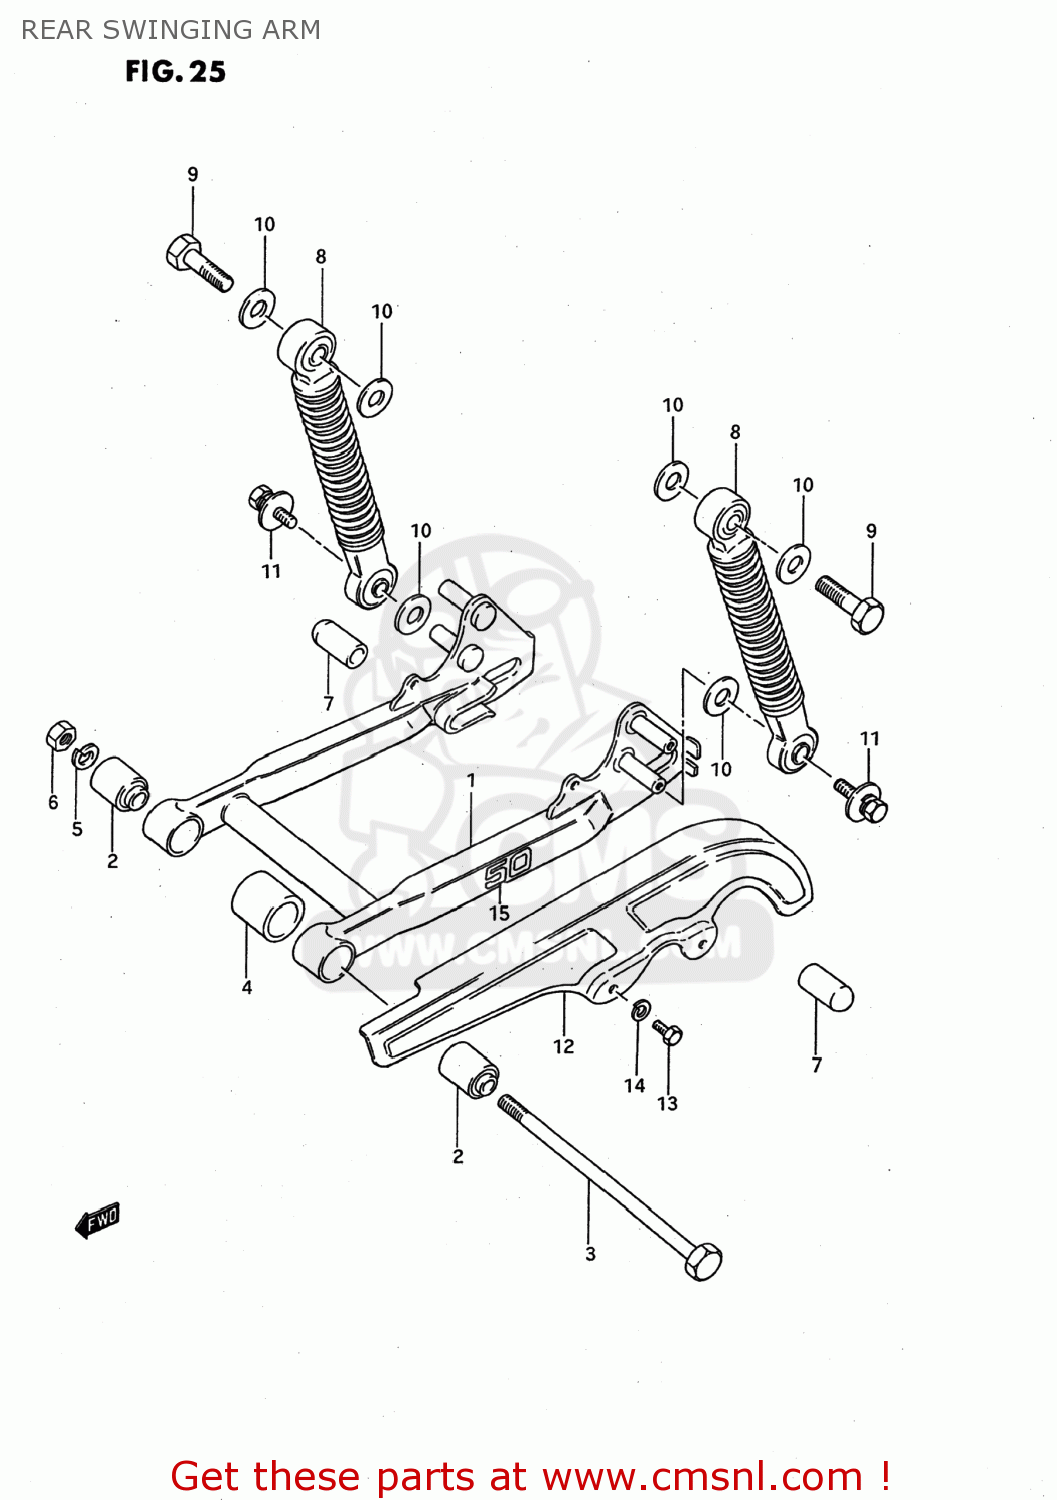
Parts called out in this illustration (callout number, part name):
1	ARM,REAR SWING
2	BUSH
3	SHAFT,RR SWINGINGARM PIVOT
4	CUSHION
5	WASHER
6	NUT
7	CAP,RR SHOCK ABSORBER BOSS
8	ABSORBER ASSY,RR SHOCK
9	BOLT,M10X1.25X
10	WASHER
11	BOLT(6X12)
12	CASE,CHAIN
13	BOLT
14	WASHER,LOCK
15	EMBLEM,SWING ARM
